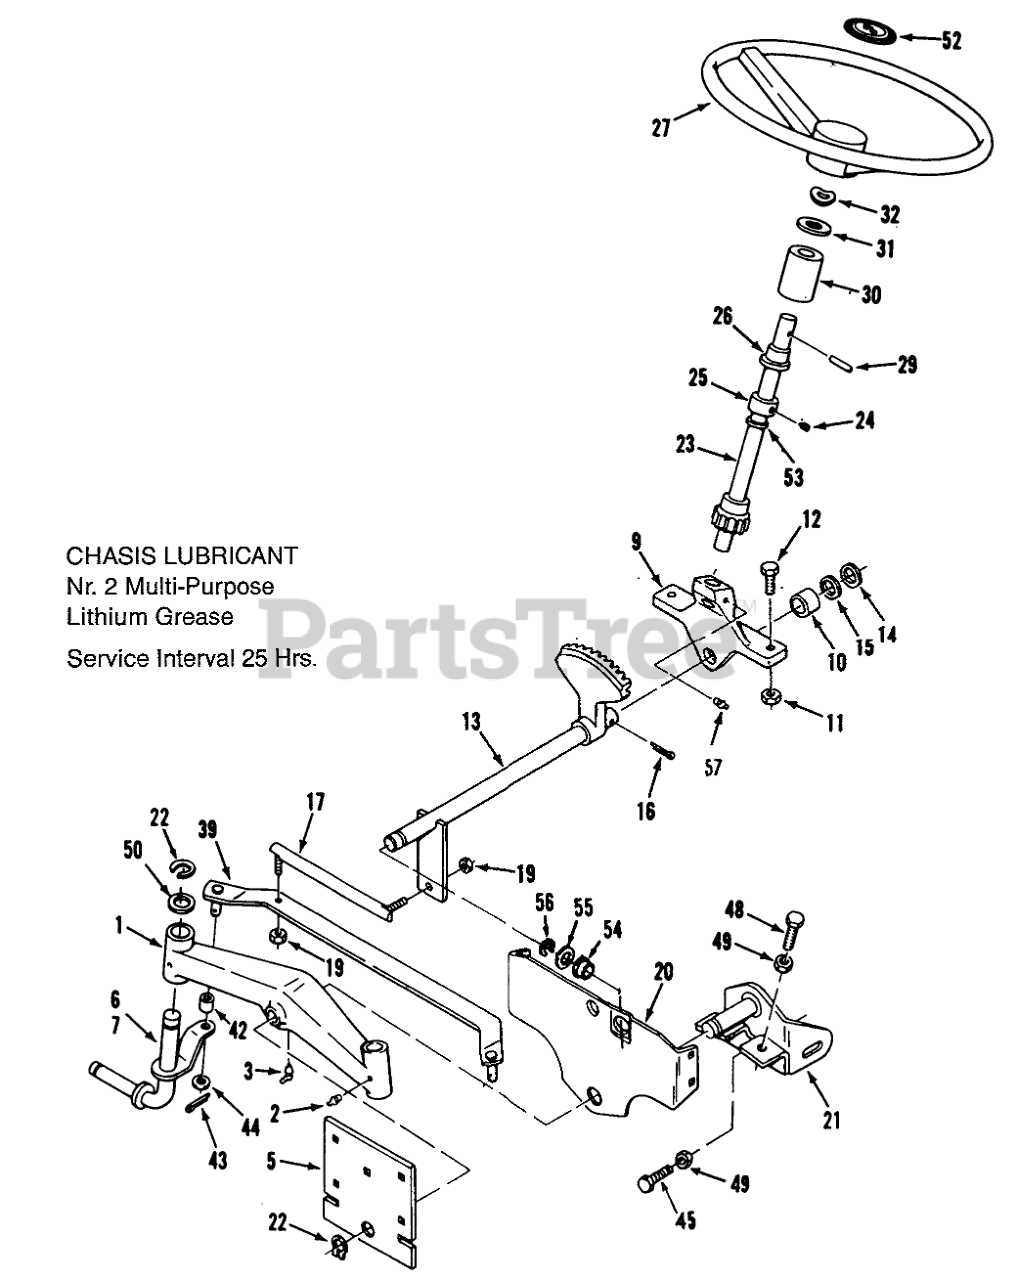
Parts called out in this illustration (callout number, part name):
1	AXLE-FRONT R
2	Zerk
3	FITTING-GREASE
5	PLATE-FRONT AXLE R
6	Front Spindle Assy RH
7	Front Spindle Assy LH
9	Support
10	BEARING-BRONZE
11	NUT
12	BOLT
13	ASSY-STRG SHAFT L B
14	WASHER-SHIM
15	WASHER
16	PIN-ROLL 1/4 X 1 1/4
17	BALL JOINT ASSY L R
19	NUT-6
20	SUPPORT AXLE R
21	ASSY-FRT HANGER R
22	Snap Ring
23	ASSY-STRG SHFT-UP R
24	SCREW-SET
25	Collar
26	BEARING-FLANGED
27	STEERING WHEEL-15"
29	Pin-Roll
30	TUBE-STEERING
31	WASHER-FLAT
32	WASHER-BOWED
39	ASSY-TIE ROD R
42	SPACER
44	WASHER
45	SCREW-HH
48	Bolt
49	Nut
50	WASHER
53	RING-RETAINING
54	BUSHING
55	WASHER SPECIAL
56	Ring
57	ZERK 90DEGREE
